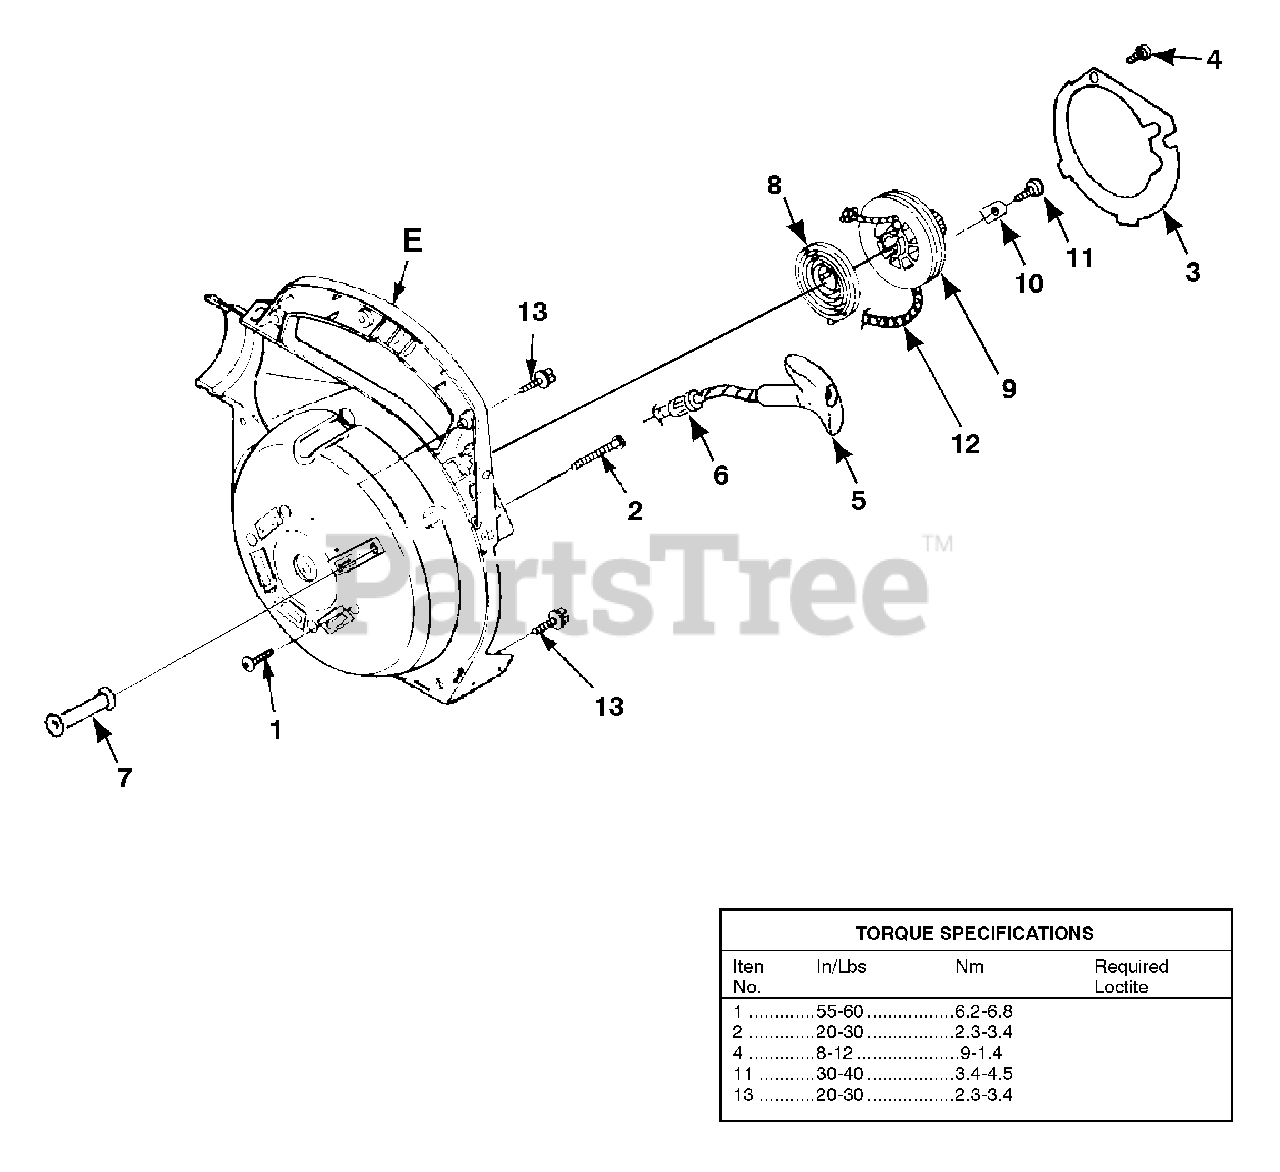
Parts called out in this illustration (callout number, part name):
1	SCREW-Thread Form. (10-24 X 3/4")
2	SCREW-Thread Form. (#10 X 1 5/8")
3	PLATE-Rotor
4	SCREW-Thread Form. (#6 X 1 3/8")
5	GRIP-Starter (Black)
6	BUSHING-Starter
7	GUIDE-Starter Rope
8	SPRING & CONTAINER
9	PULLEY-Starter
10	BRACKET-Retaining
11	SCREW-Thread Form. (#10 X 1/2")
12	ROPE-Starter
13	SCREW-Thread Form. (10-24 X 3/4")
E	VOLUTE HOUSING & STARTER
